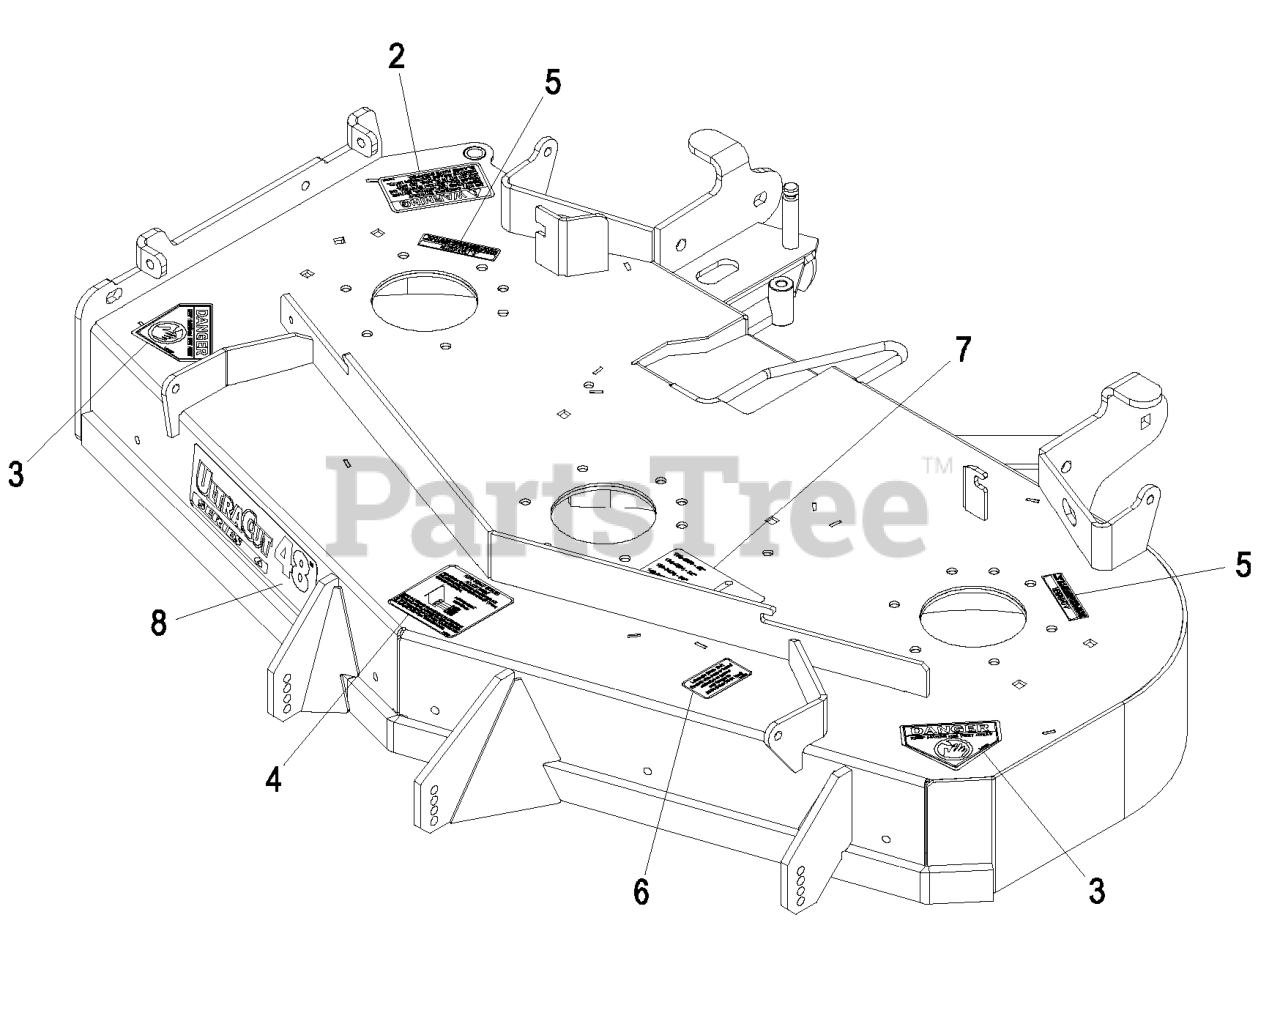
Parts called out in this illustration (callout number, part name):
2	DECAL-WARNING, DISCHARGE
3	DECAL-DANGER
4	DECAL,ANTISCALP
5	DECAL-COVER, MISSING
6	DECAL,BOLT TORQUE
7	DECAL,BELT ROUTING
8	DECAL,ULTRACUT 48 SERIES
